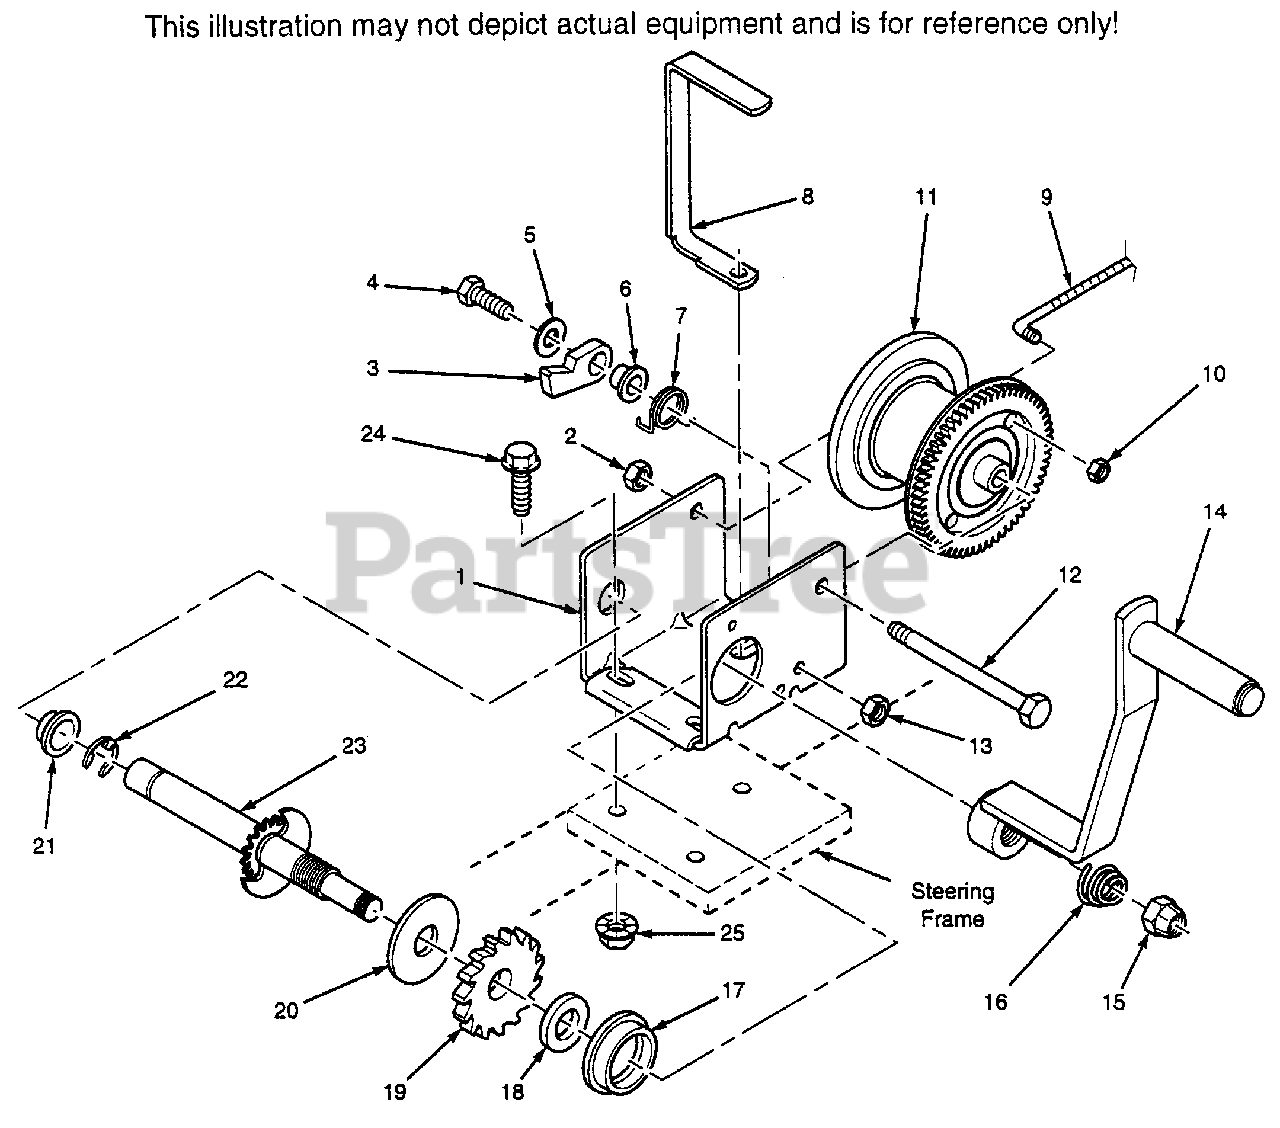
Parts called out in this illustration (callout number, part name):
1	WINCH ASSEMBLY(INCL. 1-7, 11-23)
2	LOCKNUT, 7/16-14
3	RATCHET PAWL
4	RATCHET BOLT
5	FLATWASHER
6	RATCHET SPACER
7	RATCHET SPRING
8	CABLE GUIDE
9	WINCH CABLE ASSEMBLY
10	HEX LOCKNUT, 1/4-28
11	WINCH REEL
12	REEL SHAFT
13	HEX LOCKNUT, 3/8-16
14	WINCH HANDLE
15	HANDLE NUT
16	HANDLE SPRING
17	SHAFT BUSHING
18	PRESSURE WASHER
19	RATCHET WHEEL
20	PRESSURE PLATE
21	SHAFT BUSHING
22	E-RING
23	DRIVE SHAFT
